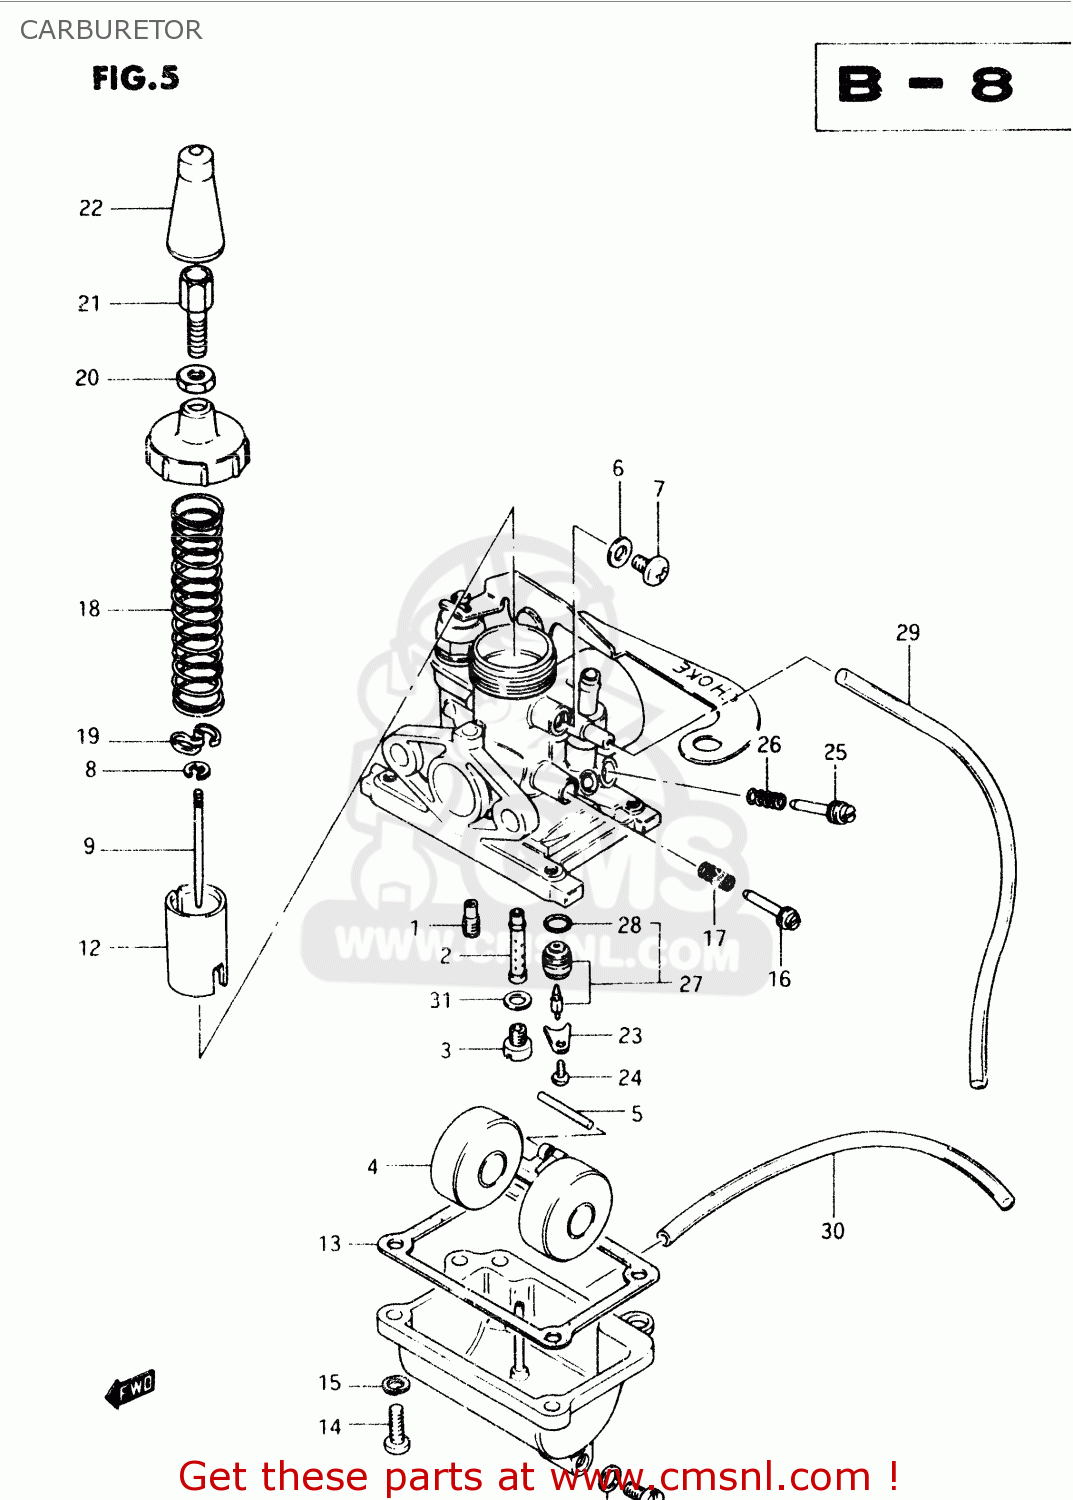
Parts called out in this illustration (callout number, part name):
1	JET
2	JET
3	JET,MAIN(67.5)
4	FLOAT
5	PIN,FLOAT
6	GASKET,DRAIN PLUG (NAS)
7	SCREW
8	CLIP,NEEDLE
9	NEEDLE,JET
10	PLUG
11	GASKET,DRAIN,PLUG (NAS)
12	VALVE,THROTTLE
13	GASKET (NAS)
14	SCREW
15	WASHER,LOCK 4M
16	SCREW,THROTTLE STOP
17	SPRING
18	SPRING,THROTTLE VALVE RETURN
19	PLATE
20	NUT
21	ADJUSTER,CABLE
22	CAP,RUBBER
23	PLATE,NEEDLE VALVE FITING
24	SCREW
25	SCREW,AIR
26	SPRING
27	VALVE ASSY,NEEDLE
28	O RING
29	HOSE
30	HOSE
31	PACKING,MAIN JET (NAS)
